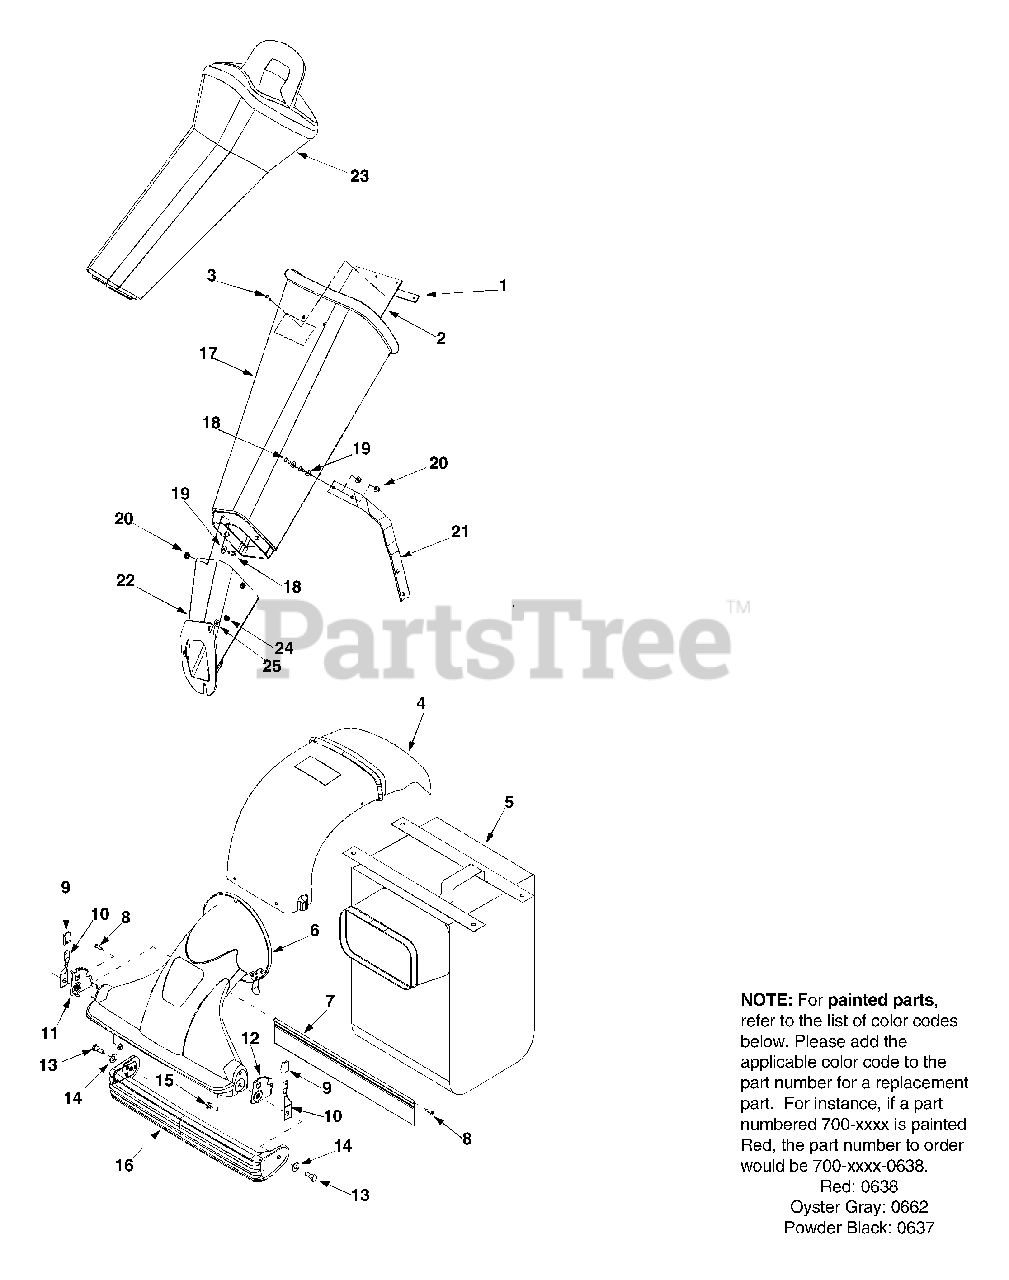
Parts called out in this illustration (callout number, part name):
1	Chute Flap Strip
2	Chute Flap
3	Pop Rivet
4	Discharge Chute
5	Bag
6	Nozzle Assembly
7	Nozzle Flap
9	Height Adjustment Knob
10	Spring Lever
13	Should er Screw
14	Flat Washer.510 x 1.12 x.060
15	Hex Flange Lock Nut 3/8-16
16	Door Assembly
17	Chipper Chute
18	Hex Cap Screw 1/4-20 x.620
19	Flat Washer .28 ID x.74 OD
20	Hex Lock Nut 1/4-20
24	Hex Nut, 5/16-18
25	Belleville Washer, .340ID x.872OD
